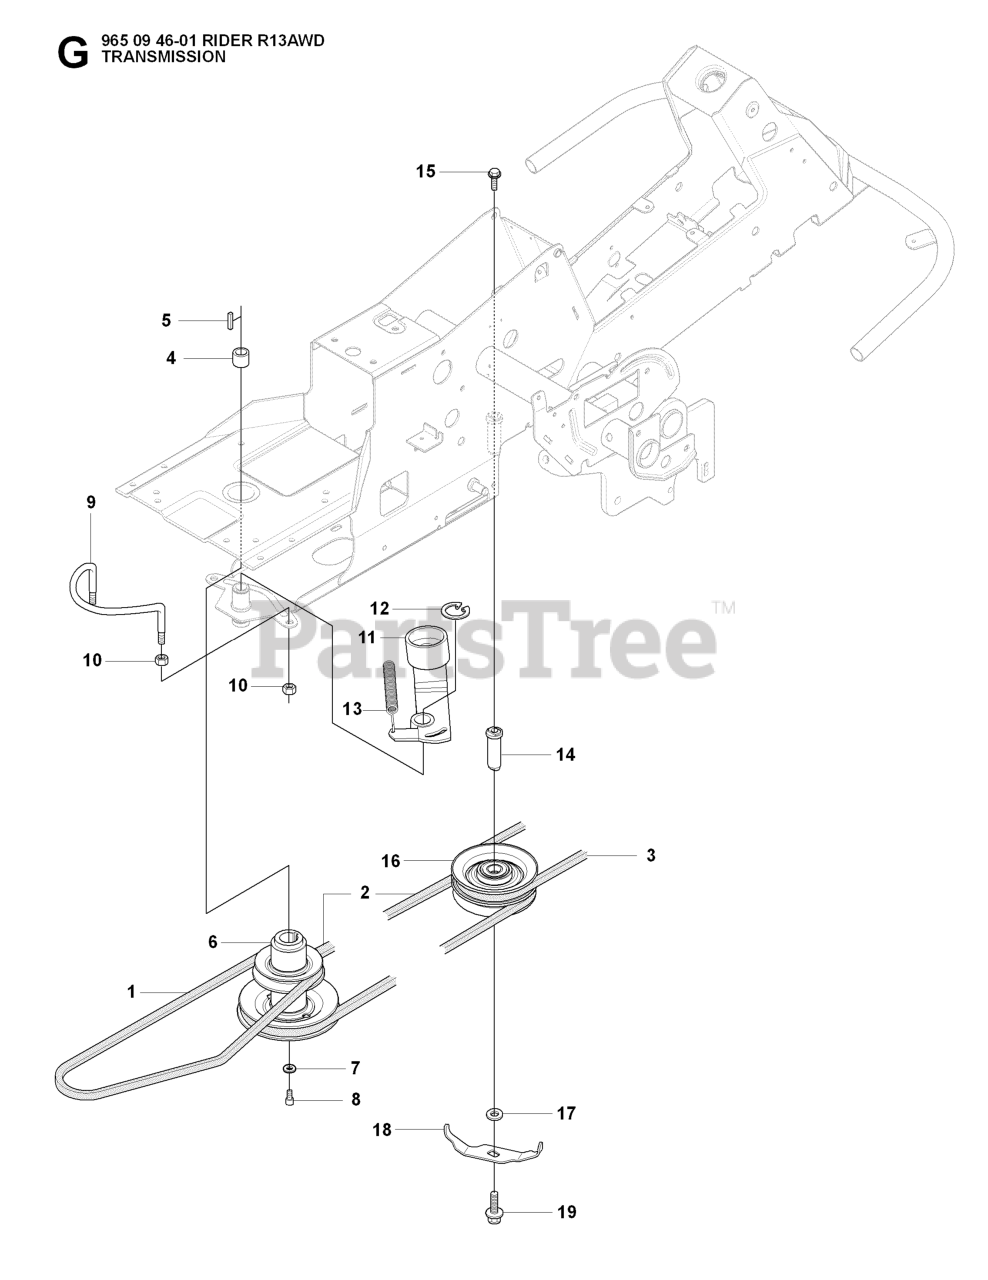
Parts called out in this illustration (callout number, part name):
1	BELT
2	BELT
3	BELT
9	BELT GUIDE
10	NUT
12	RETAINING RING SGA 25
14	SHAFT
18	BELT GUIDE
19	BOLT
